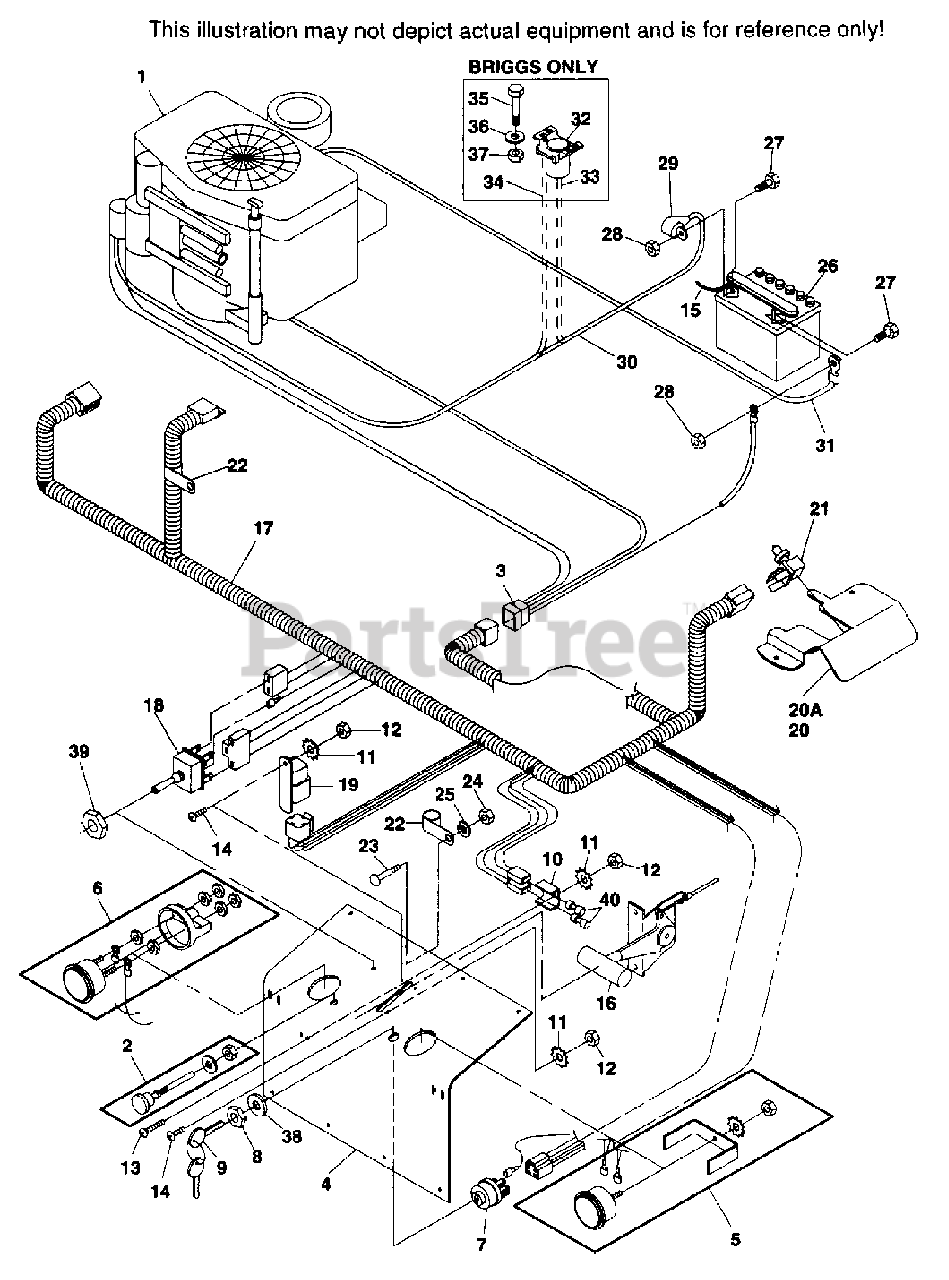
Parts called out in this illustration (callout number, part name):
1	ENGINE
2	CHOKE CONTROL
3	ADAPTER
4	KICK PLATE
5	HOUR METER
6	AMMETER
7	KEY SWITCH(INCLUDES MOUNTING HARDWARE)
8	HEX NUT, 5/8-32"
9	KEY & RING ASSEMBLY
10	BRACKET, FUSE HOLDER
11	LOCKWASHER #10 EXTERNAL TOOTH
15	OVERFLOW TUBE
16	THROTTLE CONTROL
17	WIRE HARNESS
18	SWITCH, MOWER ENGAGEMENT
19	RELAY
20	NEUTRAL LOCK BRACKET, RH
20A	NEUTRAL LOCK BRACKET, LH
21	SWITCH NEUTRAL LOCK
26	BATTERY
29	RUBBER BOOT
31	BATTERY CABLE, 27" BLACK
32	SOLENOID
33	BATTERY CABLE, 18" RED
34	BATTERY CABLE, 13-3/4" RED
38	LOCKWASHER, 5/8" INTERNAL
39	HEX NUT, 1/2-27
40	BLADE TYPE FUSE, 20 AMP
